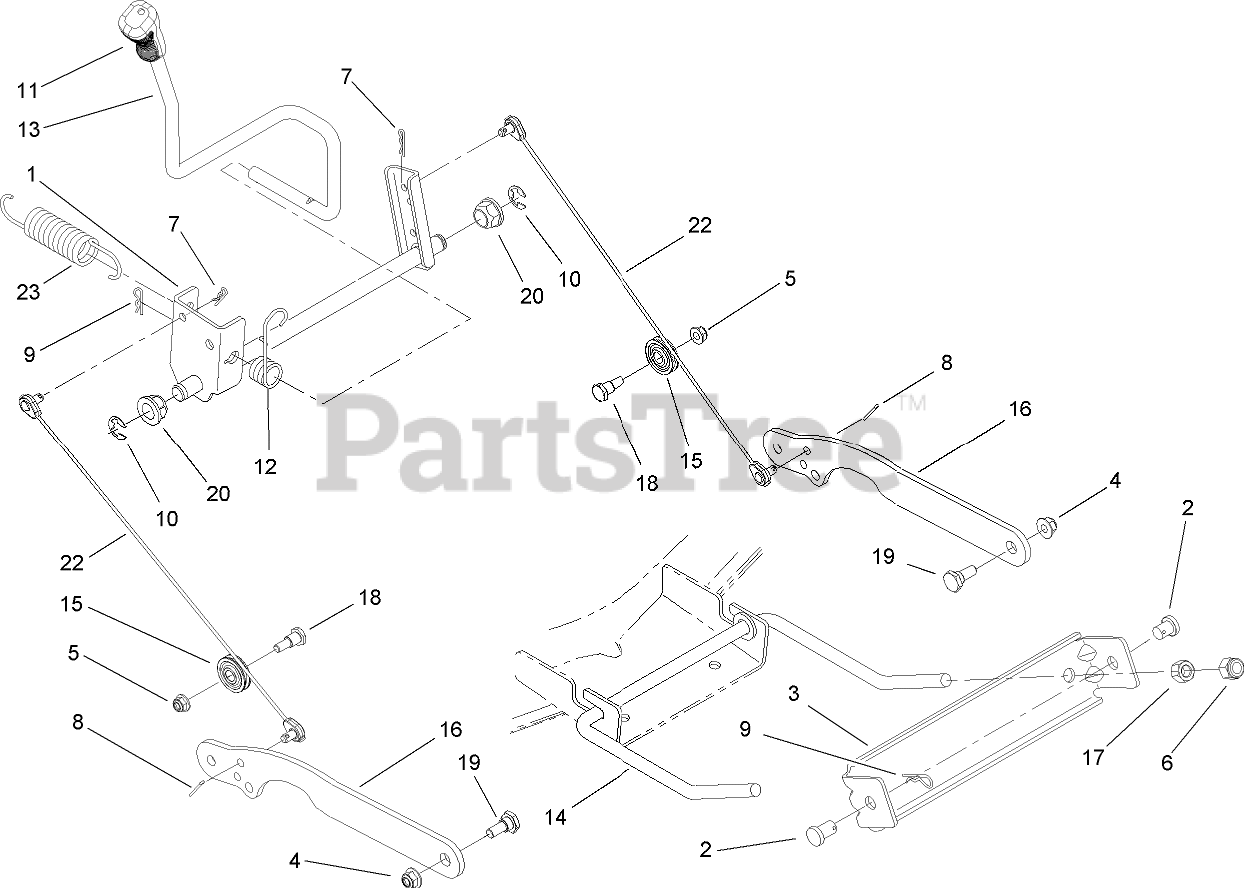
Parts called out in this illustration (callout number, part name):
1	LIFT SHAFT ASM
2	PIN-BRACKET, LIFT
3	BRACKET-STABILIZER
4	NUT-LOCK, FLANGE
5	NUT-LOCK, FLANGE
6	NUT-LOCK, HEX (NYLON)
7	PIN-COTTER
8	PIN-COTTER
9	PIN-HAIR
10	RING-E
11	GRIP-HANDLE
12	SPRING-TORSION
13	HANDLE-LIFT
14	ROD-FRONT, ADJUST
15	PULLEY-ROLLER
16	LINK-DECK, LIFT
17	NUT-HEX
18	BOLT-SHOULDER
19	BOLT-SHOULDER
20	BEARING-FLANGE
22	CABLE-LIFT
23	SPRING-LIFT, ASSIST
